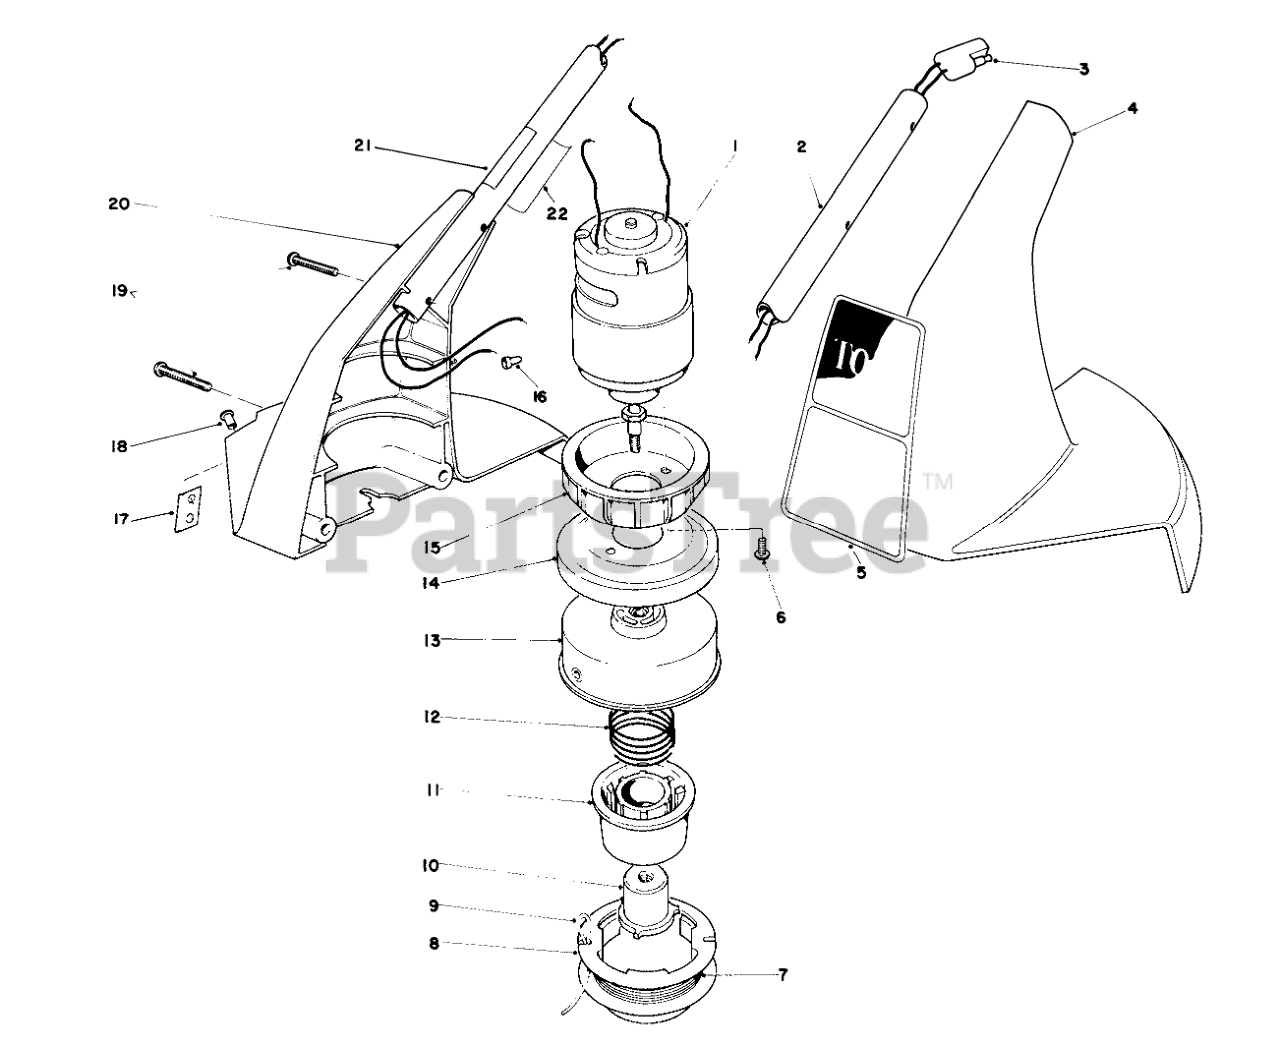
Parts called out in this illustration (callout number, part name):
1	MOTOR ASM
2	EXTENSION HANDLE
3	WIRING HARNESS LOWER
4	Housing-L.H.
5	DECAL - MOTOR HSG CSA
6	Screw
7	Cutting Line (12- .05 Dia.)
8	CAP-SPOOL
9	Cutting Line (30- .05 Dia.)
10	DRIVER
11	CORE - SPOOL
12	Spring
13	Drum w/Eyelet
14	DRUM CUP
15	Casting-Heat Sink
16	Connector
17	Knife Blade
18	Rivet
19	SCREW-PLASTITE
20	R.H. Motor Housing (Incl. Ref. #17 & 18)
21	REP. SERIAL PLT
22	Decal
